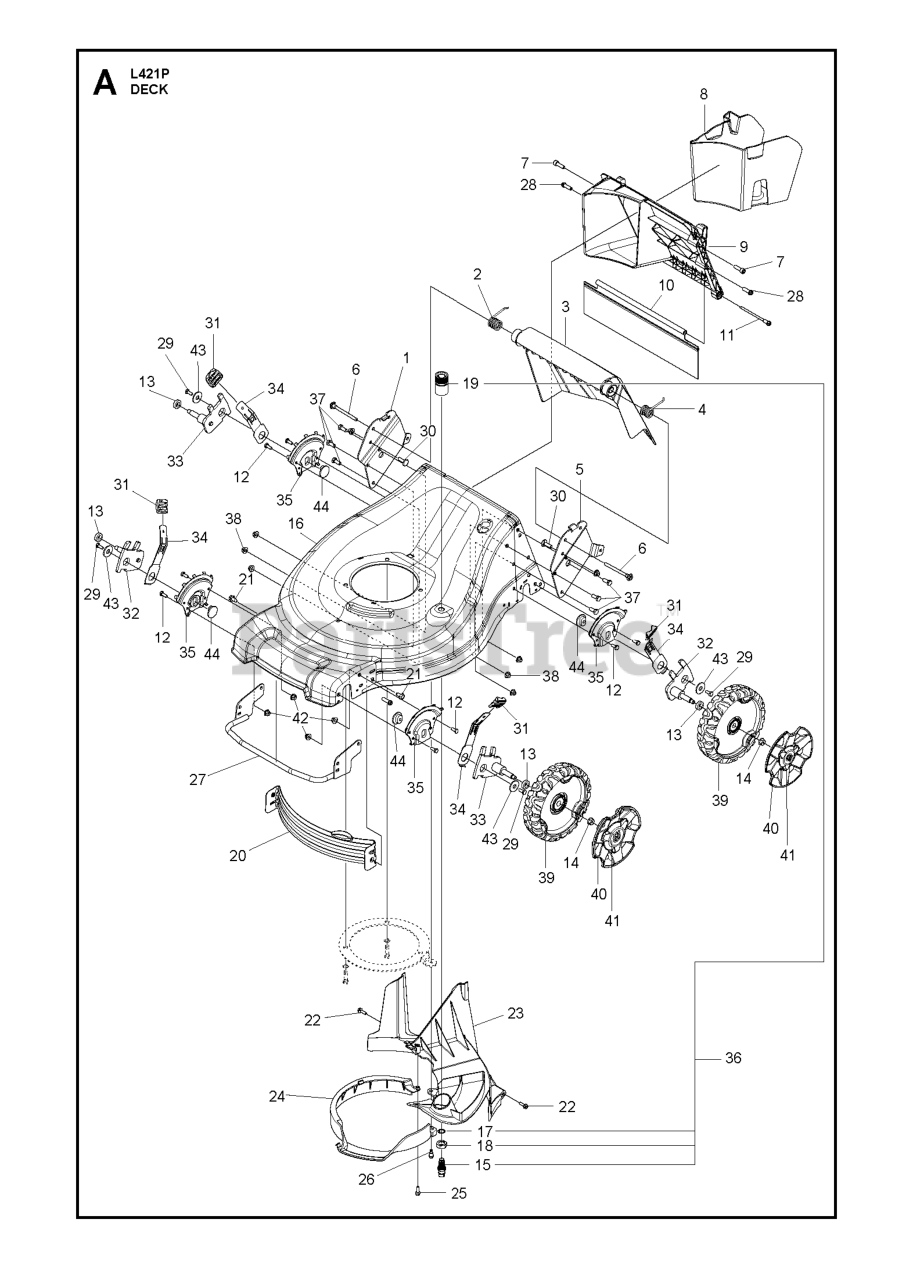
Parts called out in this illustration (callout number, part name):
1	HANDLE BRACKET RIGHT, 21 COMME
2	TORSION SPRING DOOR, RH, 21 CO
3	DOOR REAR, 21IN EFF GRAY MS-49
4	TORSION SPRING DOOR, LH, 21 CO
5	HANDLE BRACKET LEFT, 21 COMMER
6	BOLT
7	SCREW.HI-LO,5/16-14 X T-45
8	PLUG.MULCH.21 EFF
9	INSERT.REAR.21 EFF
10	SKIRT.REAR.21 EFF
11	SCREW.HI-LO.5/16-14 X 4.10
12	BOLT
13	O-RING..070X.487.NEOPRENE
14	NUT.HEX.FLANGE.3/8-16.LO(3 2)
15	WASHOUT.PORT.ZINC.RGD.22+
16	HOUSING ASSY KIT 21EFF.COMM.66
17	WASHER.LOCK.INTERNAL.TOOTH
18	LOCKNUT.HEX.WITH.O-RING
19	COUPLING.QUICK CONNECT
20	BAFFLE.FRONT.21 EFF
21	BOLT.5/16HEX.WHS.HD
22	SCREW.HI-LO.13-16X.750.375XDRV
23	COVER.BELT/REAR BAFFLE.21 EFF
24	RING.STRIPPER.21 EFF
25	SCREW.HI-LO.13-16X.750.375XDRV
26	BOLT SHOULDER_1/4-20_TRILOB
27	BUMPER.ASM.GRY.498
28	SCREW.HI-LO,5/16-14 X T-45
29	BOLT
30	BOLT.CARRIAGE.5/16-18
31	SELECTOR KNOB
32	ARM AXLE ARM ASSM, RF, LR, 21
33	AXLE AXLE ARM ASSM. LF,RR BLAC
34	SPRING.SELECT.4PT.21EFF.004
35	ADJUSTER HEIGHT BLACK AUTOPHOR
36	KIT.WASH-OUT.PORT
37	BOLT.FIN.HEX.5/16-18X3/4
38	NUTNYLOK.FLRANGE.5/16-18
39	WHEEL ASSY 210, IDLE, MEDIUM
42	NUT.FLANGE.1-4-20-SERR
43	WASHER
44	AXLE PIVOT AXLE CLEAR ZINC
